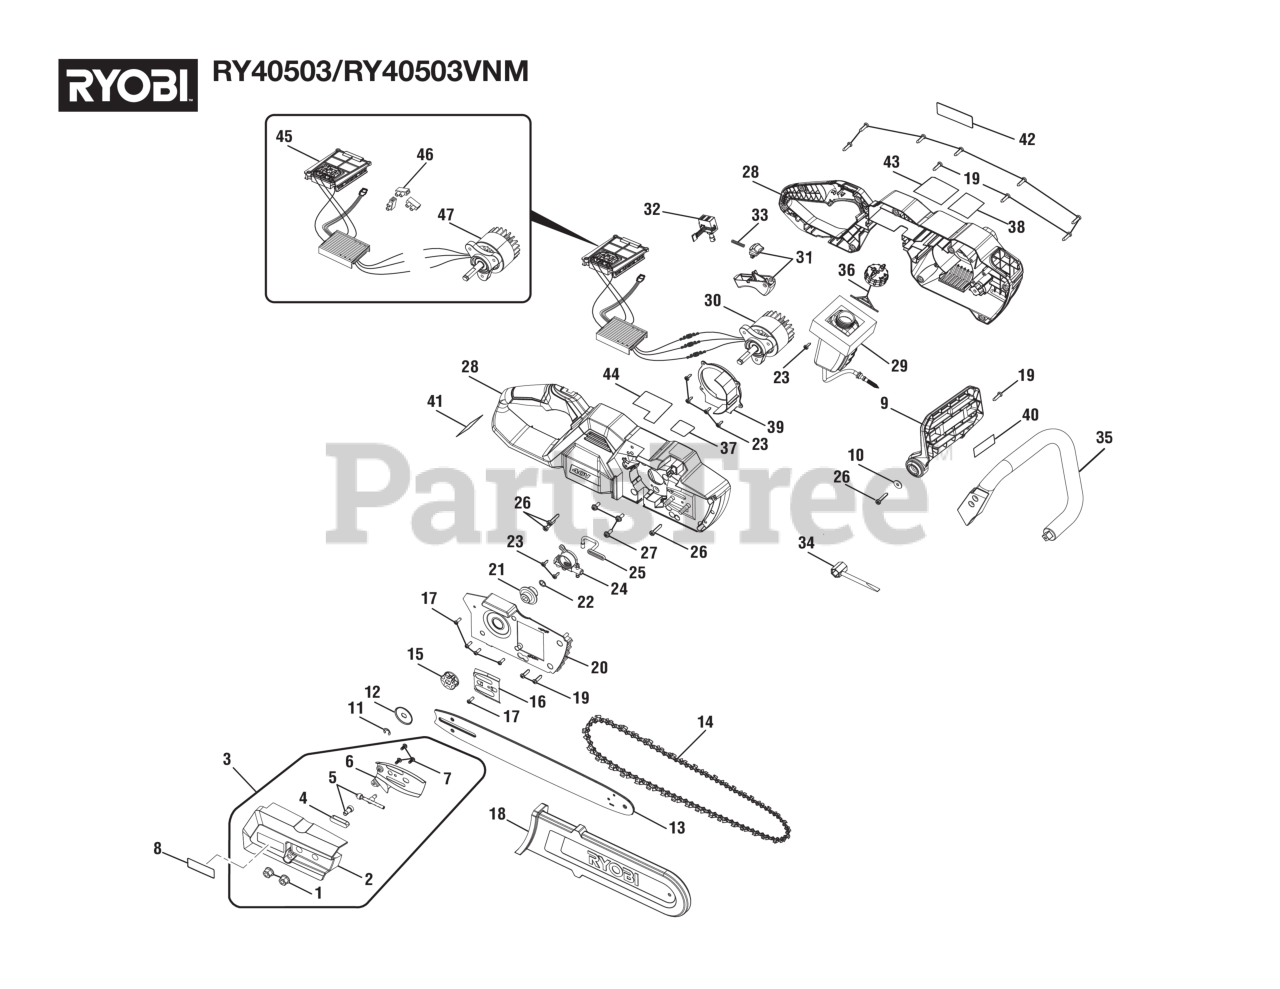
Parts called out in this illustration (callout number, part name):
1	Hex Nut (5/16-18 Flange)
2	Bar Cover
3	Bar Cover Assembly
4	Rubber Plate
5	Driving Adjustment Gear Assembly
6	Guide Plate
7	Screw (M4 x 10 mm, T20 Torx Pan Hd.)
8	Bar Cover Logo Label
9	Guard Assembly
10	Washer (ID5.2 x OD16 x 1.5t)
12	Washer (Special)
13	Bar (14 in.)
14	Chain (14 in.)
16	Guide Plate Bar
17	Screw, M4-18 x 12mm, T20 Torx Pan Head
19	Screw (T20 x 15 mm)
20	Cover Housing
21	Oil Pump Drive
23	Screw (M4.2 x 12 mm, T20 Torx Pan Hd.)
25	Oil Output Tube
26	Screw (T20 x 20 mm)
27	Screw, T25, M5X8, Steel, Black ZincePlat
28	Housing Assembly
29	Oil Tank Assembly
30	Motor, Motor Controller and Battery Connector Assembly
31	Switch Trigger & Lock Out Button Assembly
33	Compression Spring (Trigger Lock)
35	Front Handle
36	Oil Tank Cap
37	Height Adjust Label
38	Warning Icon Label (Left)
39	Volute Cover
40	Logo Label
41	Data Label
42	Motor Side Logo Label
43	Warning Label (English/Spanish, Left)
44	Warning Label (English/French, Right)
45	Motor Controller and Battery Connector Assembly
46	Terminal Block w/Screw
47	Motor
